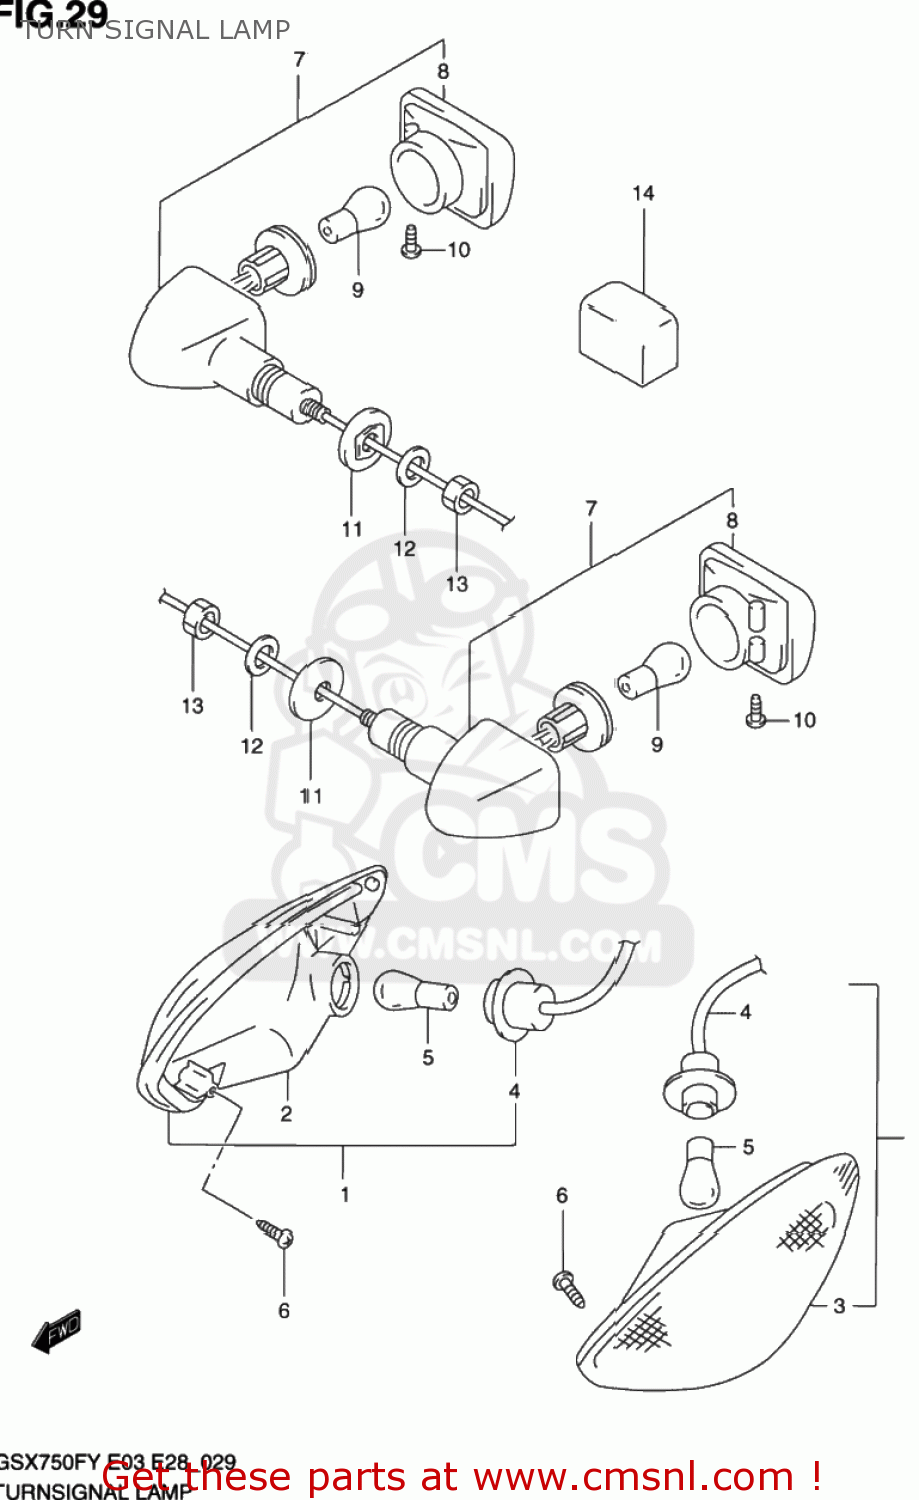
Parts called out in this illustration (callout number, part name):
1	LAMP ASSY,FR TURN SIGNAL,R
2	LAMP UNIT,R
3	LAMP UNIT,L
4	SOCKET & CORD
5	BULB(12V21W)
6	SCREW
7	LAMP ASSY,RR TURNSIGNAL,R
8	LAMP UNIT
9	BULB(12V21W)
10	SCREW
11	SPACER,RR TURNSIGNAL
12	WASHER(10.5X30X2.3)
13	NUT
14	RELAY ASSY,TURNSIGNAL LAMP
